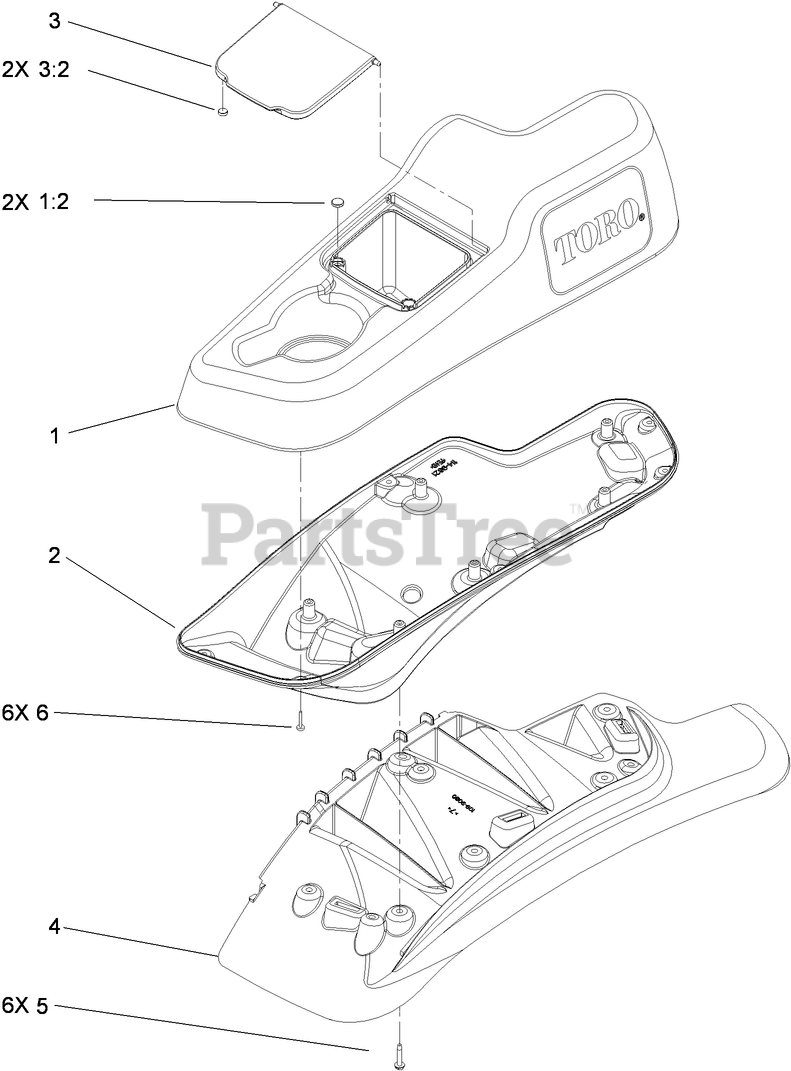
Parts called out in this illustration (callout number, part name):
1	LH CONSOLE TOP ASM
2	LH LOWER CONSOLE ASM
3	LID ASM
3:2	MAGNET
4	FENDER-LH
5	SCREW-THREAD FORMING
6	SCREW-PPH
